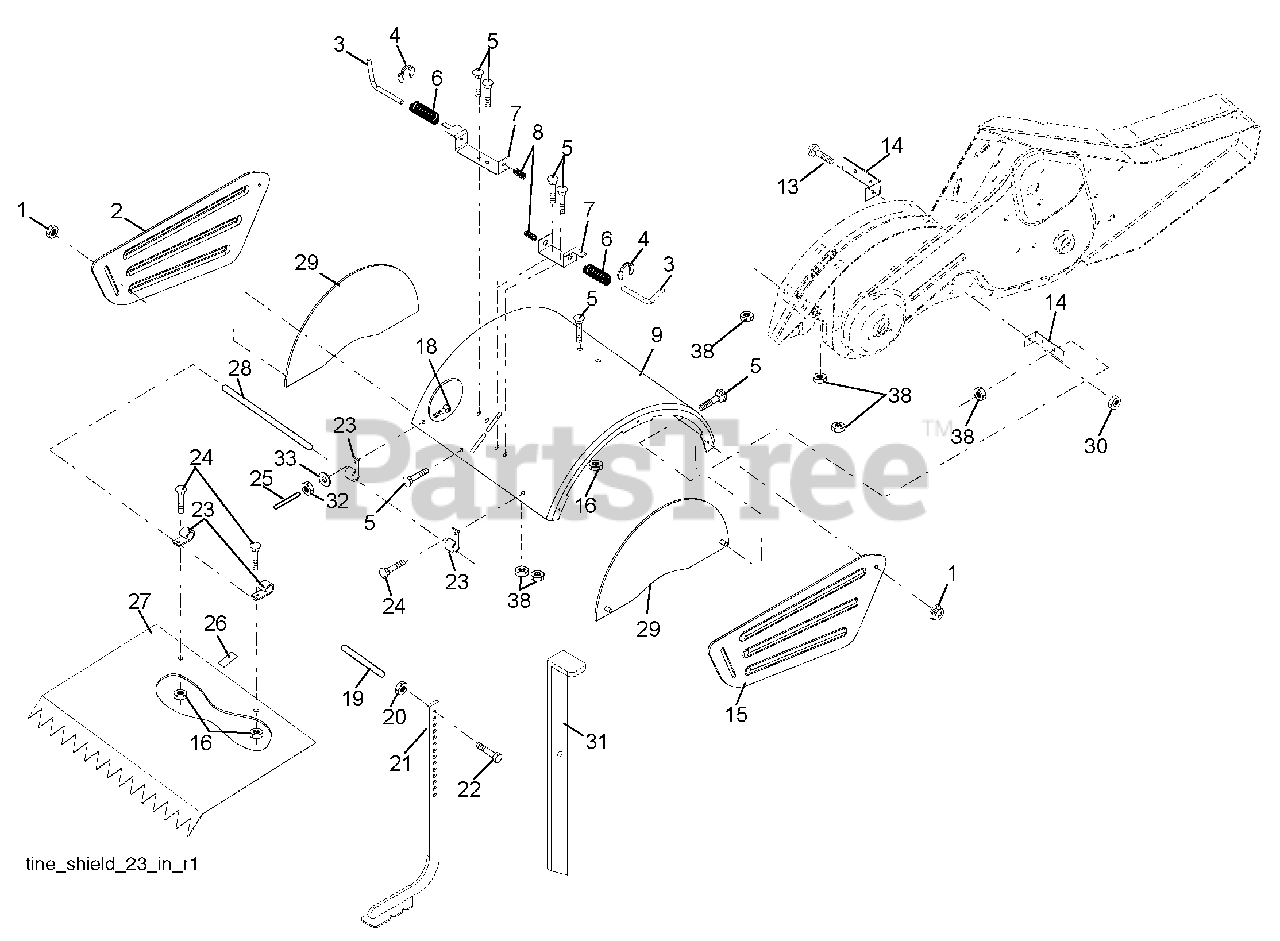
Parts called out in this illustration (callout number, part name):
1	Nut, Lock Hex Flange 5/16-18
2	Shield, Side, Outer L. H.
3	Pin, Stake, Depth
4	Ring, Klip
5	Bolt 5/16-18 x 3/4 ZNC
6	Spring
7	Bracket, Latch
8	Spring, Depth Stake
13	Bolt, Carriage 5/16-18 x 1-1/4
14	Bracket, Shield Tine
15	Shield, Side, Outer R.H.
16	Nut, Hex Flange 1/4-20 unc
18	Bolt, Carriage 1/4-20 x 1-1/4 Gr. 5
19	Grip
20	Nut, Hex 3/8-16
21	Stake, Depth
22	Bolt, Hex 3/8-16 x 2
23	Hinge
24	Bolt, Carriage 1/4-20 x 1/2 Gr. 5
25	Cap, Vinyl
26	Pad, Idler
27	Shield, Leveling
28	Pin, Hinge
29	Shield, Side
30	Locknut, Flange 5/16-18
31	Stake Depth Drag
32	Nut Fin Hex 1/4-20 unc
33	Washer Lock Hvy Helical 1/4
38	Nut, Keps 5/16-18 unc
